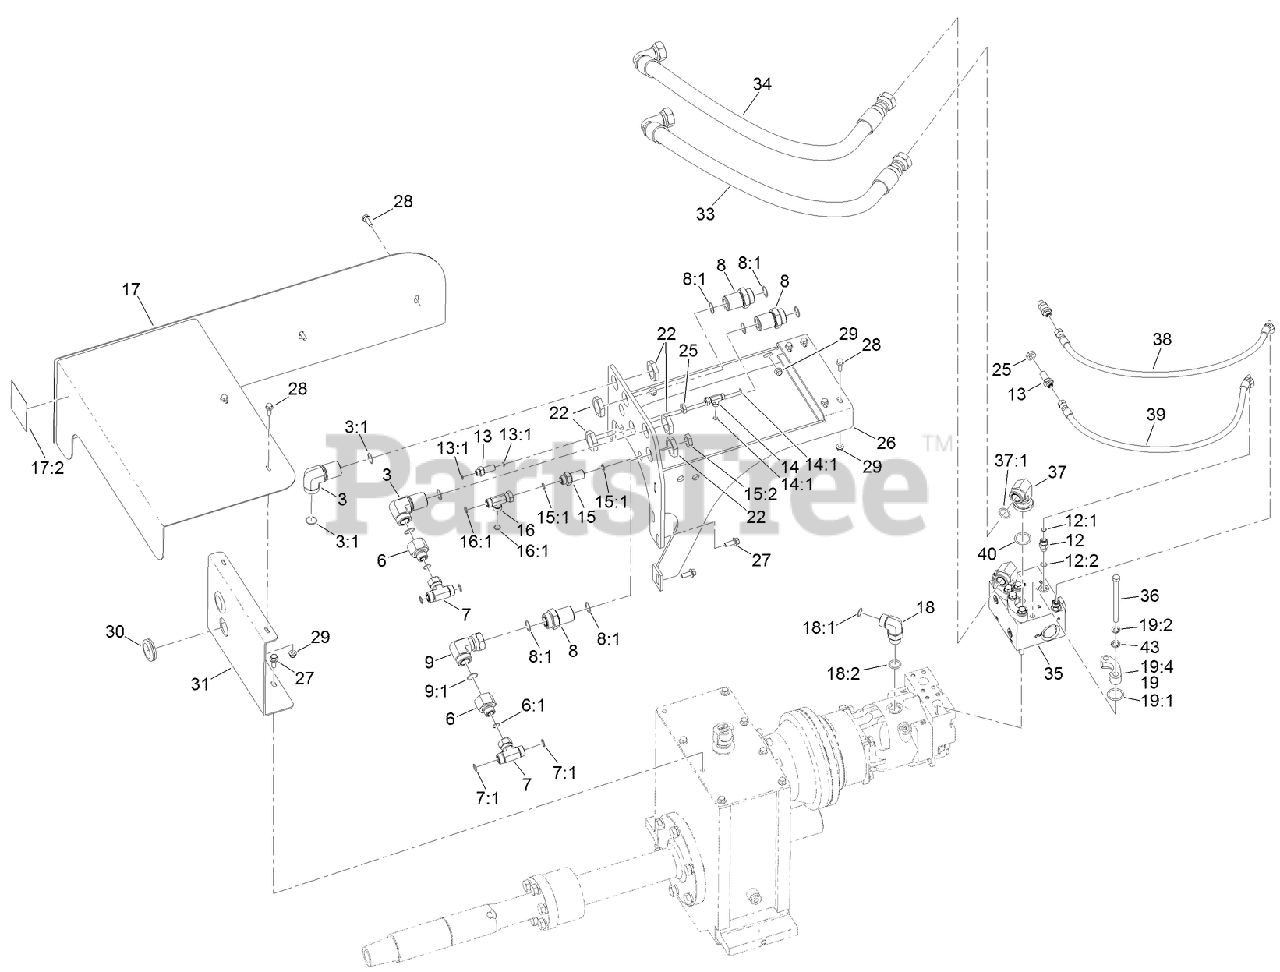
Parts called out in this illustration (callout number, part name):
3	FITTING-ELBOW, 90
3:1	O-RING
6	FITTING-REDUCER
6:1	O-RING
7	FITTING-HYD, TEE
7:1	O-RING
8	ADAPTER-HYD
8:1	O-RING
9	FITTING-SWIVEL, 90 DEG
9:1	O-RING
12	FITTING-STRAIGHT
12:1	O-RING
12:2	O-RING
13	UNION-BULKHEAD
13:1	O-RING
14	FITTING-HYD
15	FITTING-BULKHEAD
15:1	O-RING
15:2	NUT-BULKHEAD
16	FITTING-HYD, TEE
16:1	O-RING
17	CARRIAGE GUARD ASM
17:2	DECAL-WARNING
18	FITTING-ELBOW-90
18:1	O-RING
18:2	O-RING
19	HYD FLANGE KIT
19:1	O-RING
19:2	SCREW-HH
22	NUT-BULKHEAD
25	NUT-LOCK
26	MOUNT-HOSE CARRIER, ROTARY
27	SCREW-HHF
28	SCREW-HHF
29	NUT-LOCK, HHF
30	GROMMET
31	PLATE-SUPPORT, GUARD
33	HYD HOSE ASM
34	HYD HOSE ASM
35	SPIKE CLIPPER MANIFOLD ASM
36	SCREW-HH
37	FITTING-ELBOW, 90 DEGREE
37:1	O-RING
38	HYD HOSE
39	HYD HOSE ASM
40	O-RING
43	SCREW-HH
